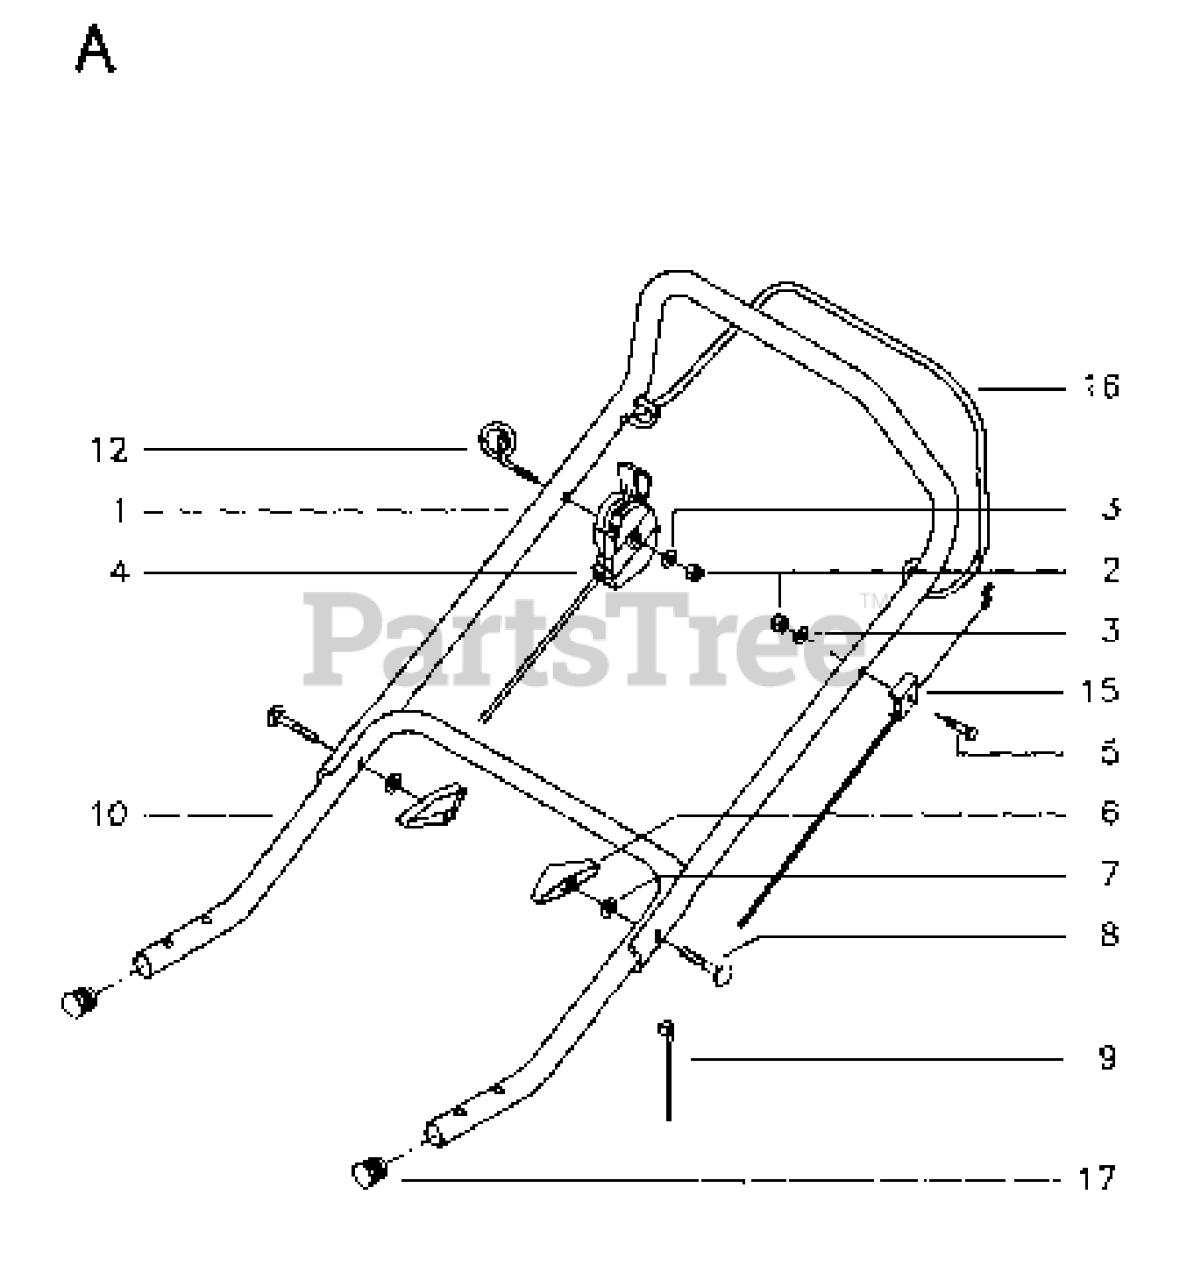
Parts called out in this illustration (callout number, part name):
2	LOCKNUT M6
4	THROTTLE TRIGGER
5	BOLT FLANGE
6	WINGNUT
15	REPL BY 532 85 16-72
